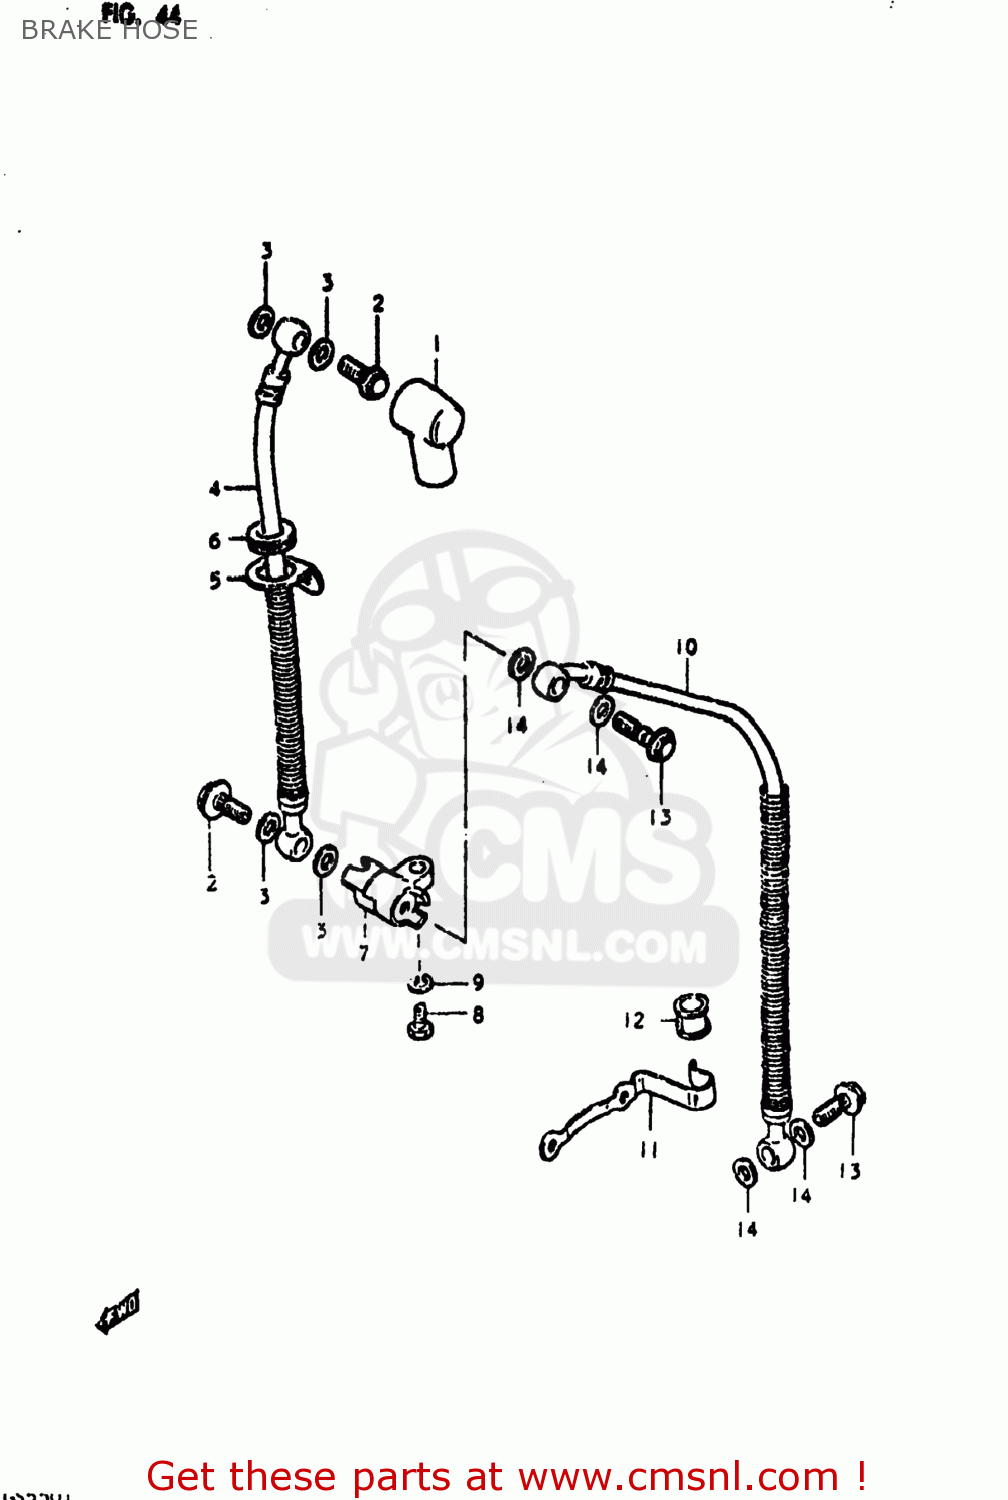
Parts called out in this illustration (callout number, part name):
1	BOOT,MASTER CYLINDER
2	BOLT,UNION
3	WASHER
4	HOSE,BRAKE NO.1
5	GUIDE,BRAKE HOSE
6	GROMMET
7	JOINT,BRAKE HOSE
8	BOLT
9	LOCK WASHER
10	HOSE,BRAKE NO.2
11	GUIDE,FRONT BRAKE HOSE
12	BUSH,BRAKE HOSE GUIDE,NO.2
13	BOLT,UNION
14	WASHER
